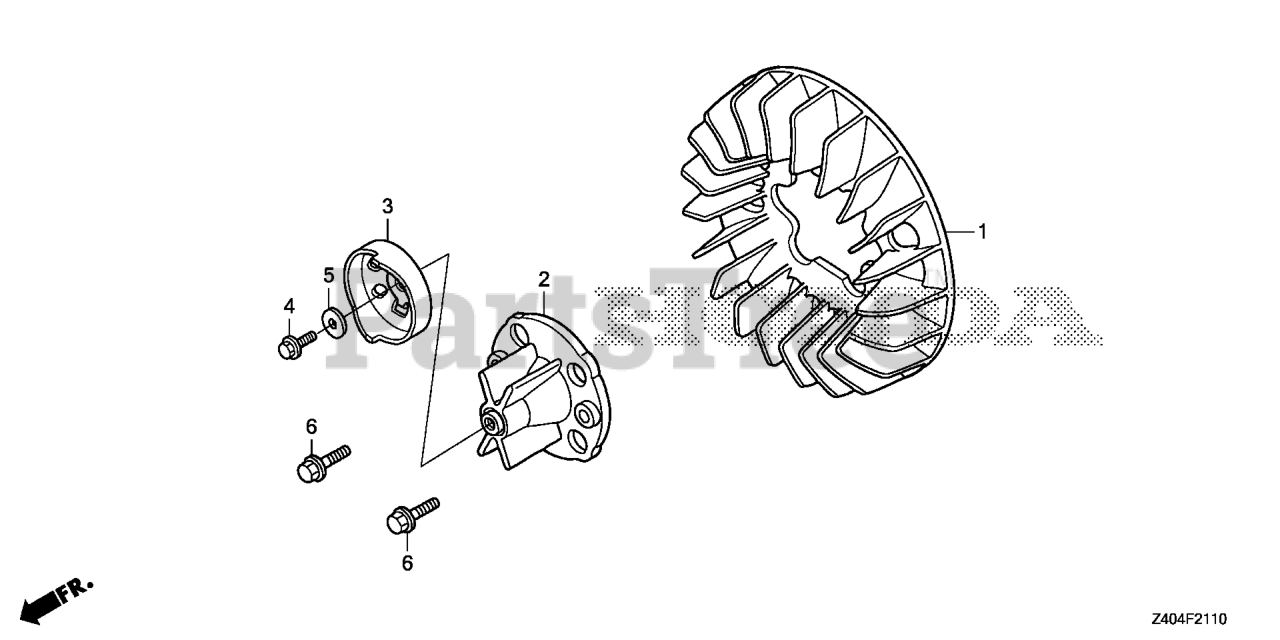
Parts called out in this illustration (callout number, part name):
1	FAN, COOLING
2	BOSS, COOLING FAN
3	PULLEY, RECOIL STARTER
4	BOLT, FLANGE (6X16)
5	WASHER, PLAIN (6MM)
6	BOLT, FLANGE (6X16)
